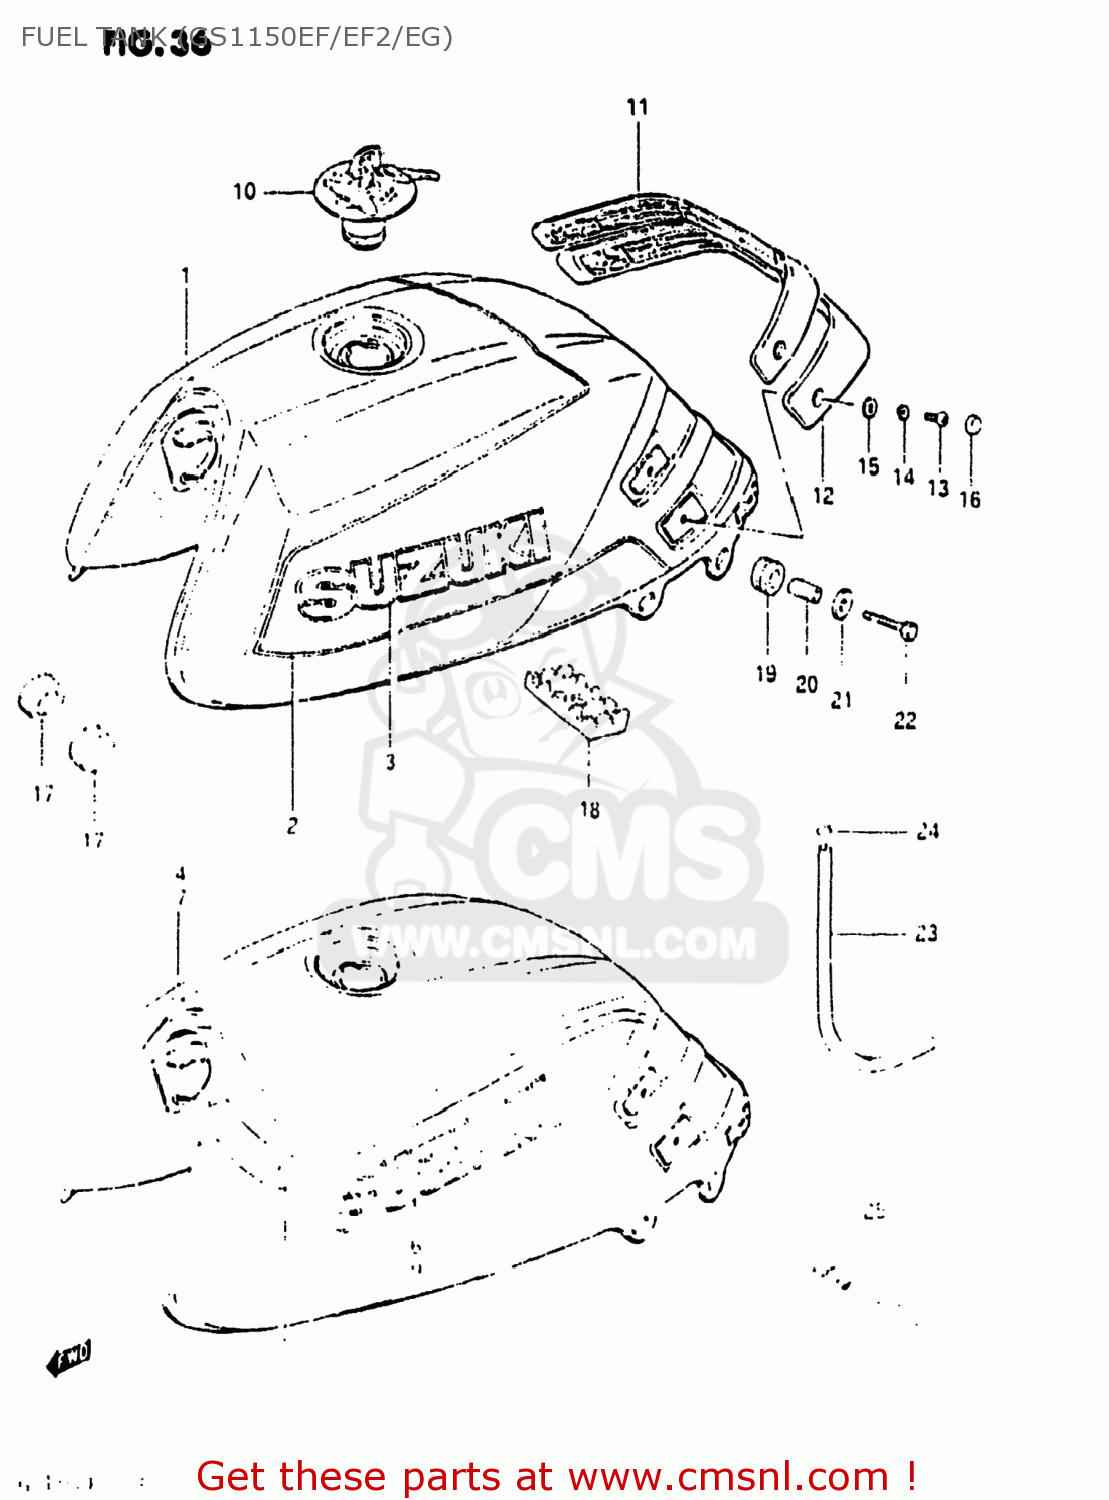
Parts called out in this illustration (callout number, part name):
1	TANK ASSEMBLY,FUEL
2	TAPE SET,FUEL TANK
3	EMBLEM
4	TANK ASSEMBLY,FUEL
5	TAPE SET,FUEL TANK
6	EMBLEM
7	TANK ASSEMBLY,FUEL
8	TAPE SET,FUEL TANK
9	EMBLEM
10	CAP SET,FUEL TANK
11	KNEE GRIP,FUEL TANK,UPPER
12	KNEE GRIP,FUEL TANK,LOWER
13	SCREW
14	LOCK WASHER
15	WASHER
16	CAP,KNEE GRIP
17	CUSHION
18	CUSHION,FUEL TANK CTR
19	CUSHION
20	SPACER (6.4X9X20)
21	WASHER (6.5X29X1.6)
22	BOLT 6X30
23	HOSE,FUEL
24	CLIP
25	CLAMP(L:187)
